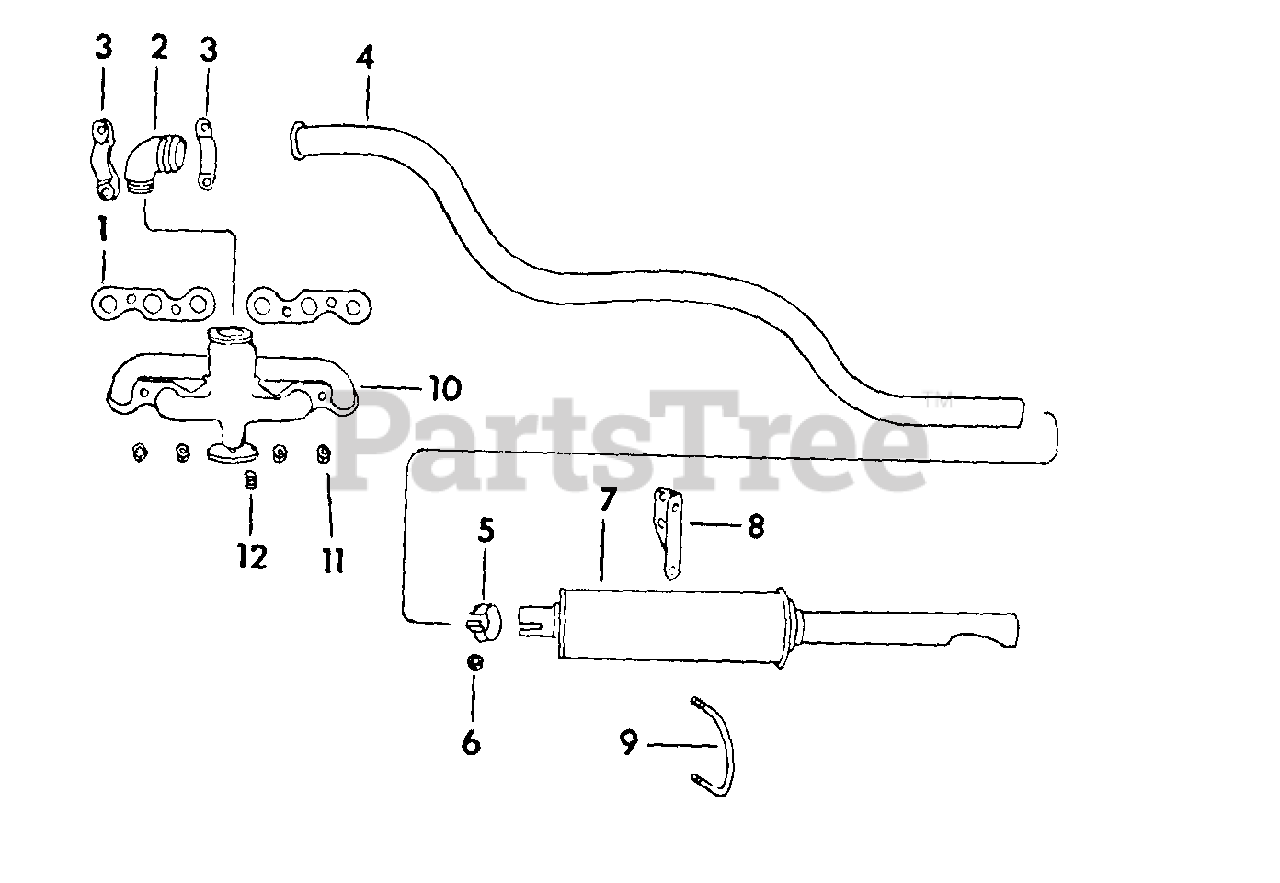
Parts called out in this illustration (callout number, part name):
1	GASKET, EXHAUST AND INTAKE MANIFOLD
2	ELBOW, EXHAUST PIPE
3	CLAMP, EXHAUST MANIFOLD
4	PIPE, EXHAUST
5	CLAMP, EXHAUST MUFFLER
6	NUT, EXHAUST MUFFLER CLAMP
7	MUFFLER, EXHAUST
8	BRACKET. MUFFLER SUPPORT
9	U-BOLT, MUFFLER
10	MANIFOLD, EXHAUST AND INTAKE
11	NUT, EXHAUST AND INTAKE MANIFOLD STUD
12	STUD, CARBURETOR
